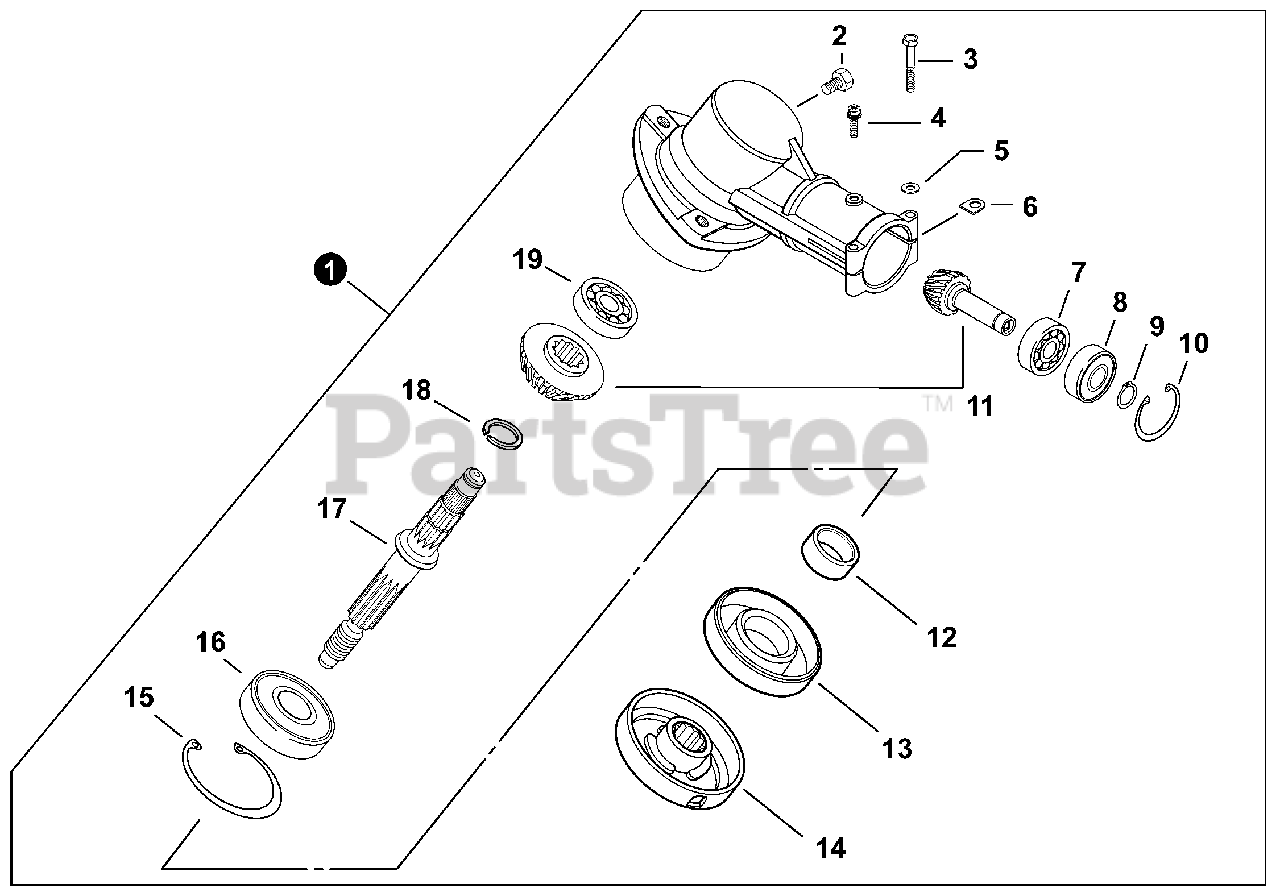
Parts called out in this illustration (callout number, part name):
1	GEAR CASE ASSY
2	BOLT M8x8
3	BOLT 5x35 SP
4	SCREW 5x10
5	WASHER, FLAT 5.5x10x0.8
6	D-WASHER
7	BEARING, BALL 6900
8	BEARING, BALL 6900Z
9	RING, SNAP 12
10	RING, SNAP 22
11	GEAR SET
12	SPACER 11.8x15x9
13	SEAL, OIL 22
14	PLATE, ADAPTOR - UPPER
15	RING, SNAP 32
16	BEARING, BALL 6201
17	SHAFT, GEAR
18	RING, SNAP 10
19	BEARING, BALL 609
